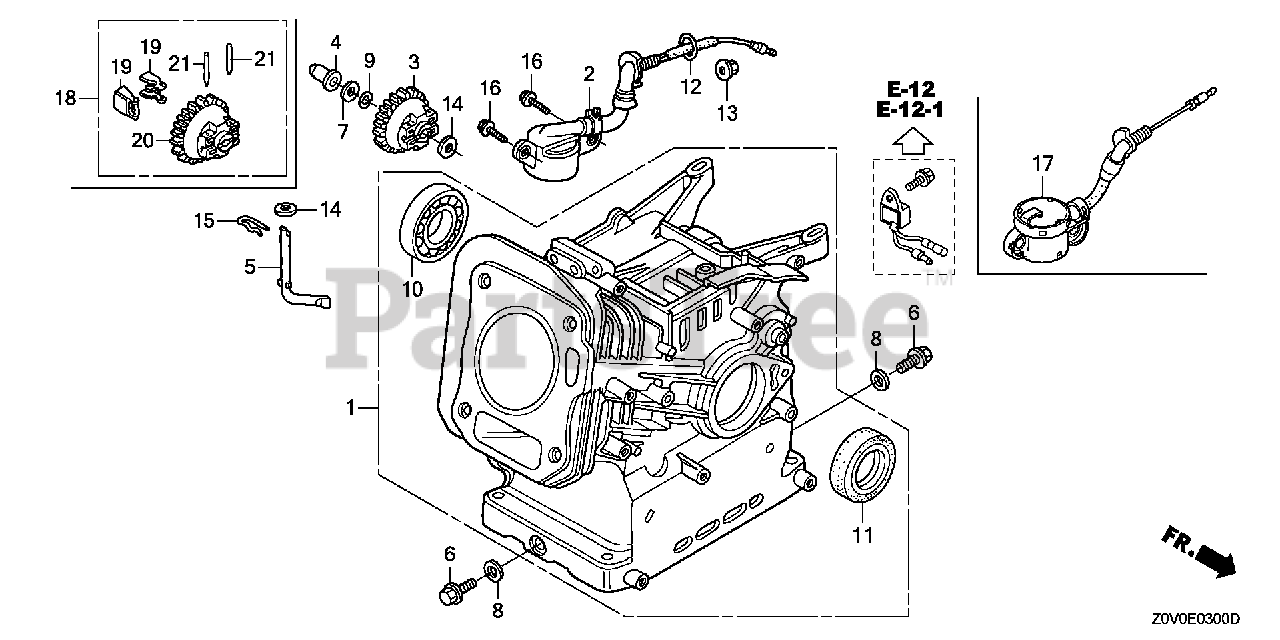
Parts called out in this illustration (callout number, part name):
1	CYLINDER ASSY.
3	GOVERNOR ASSY.
4	SLIDER, GOVERNOR
5	SHAFT, GOVERNOR ARM
6	BOLT, DRAIN PLUG
7	WASHER, THRUST (6MM)
8	WASHER, DRAIN PLUG (10.2MM)
9	CLIP, GOVERNOR HOLDER
10	BEARING, RADIAL BALL (6205TMB) (NTN)
10	BEARING, RADIAL BALL (6205) (NSK)
11	OIL SEAL (25X41X6) (NOK)
12	O-RING (13.5X1.5) (ARAI)
12	O-RING (14MM) (NOK)
13	NUT, FLANGE (10MM)
14	WASHER, PLAIN (6MM)
15	PIN, LOCK (8MM)
16	BOLT, FLANGE (6X12)
17	SWITCH ASSY., OIL LEVEL
